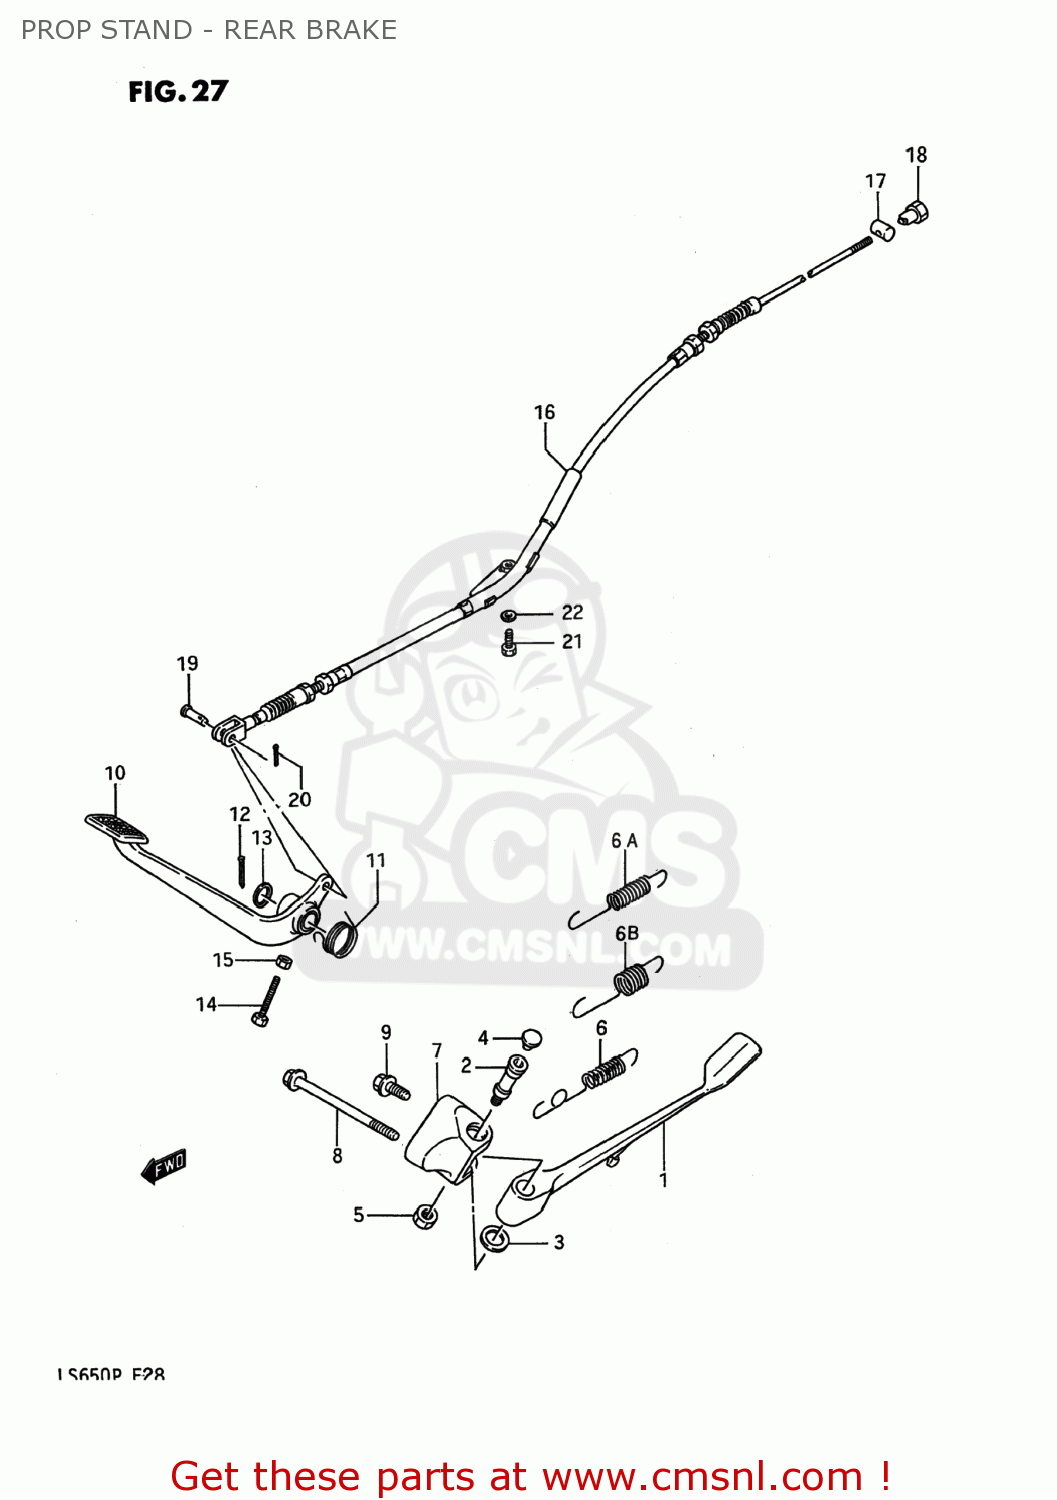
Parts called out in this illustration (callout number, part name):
1	STAND,PROP
2	BOLT,PROP STAND
3	THRUST WASHER
4	CAP,PROP STAND BOLT
5	NUT
6	SPRING
6A	SPRING
6B	SPRING
7	BRACKET,PROP STAND
8	BOLT(10X105)
9	BOLT 10X25
10	PEDAL,BRAKE
11	SPRING
12	COTTER PIN
13	BOLT
14	NUT 6MM
15	WASHER (16.5X42X2.6)
16	CABLE,RR BRAKE
17	PIN
18	NUT (6MM)
19	PIN(L:17.5)
20	PIN
21	BOLT 6X16
22	WASHER,LOCK
